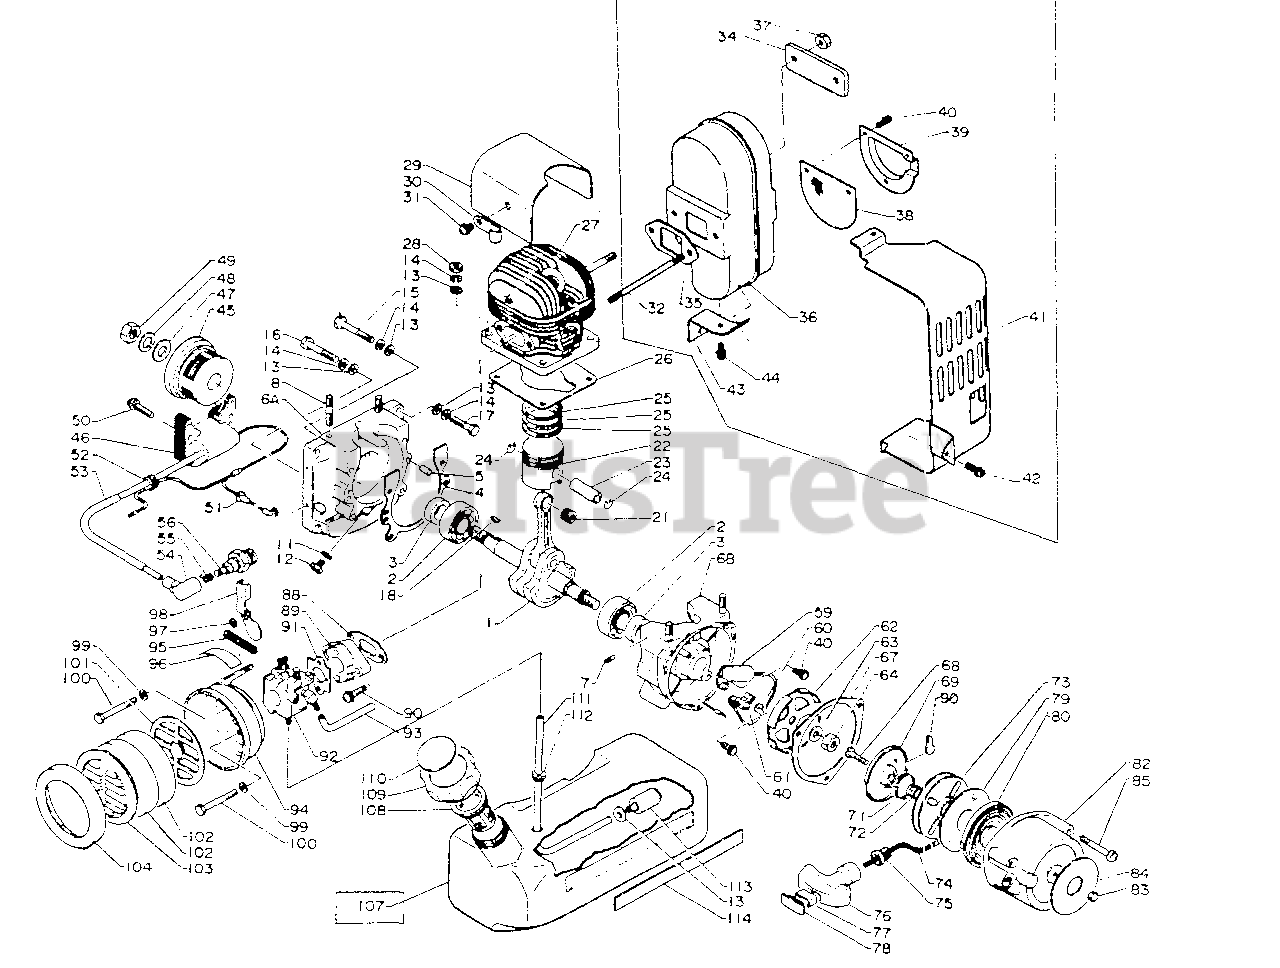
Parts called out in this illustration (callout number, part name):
1	CRANKSHAFT ASSY
2	BEARING, BALL 6202
3	SEAL, OIL
4	GASKET, CRANKCASE
5	PIN, LOCATING 5×10
6	CRANKCASE KIT
6A	CRANKCASE KIT
7	CONNECTOR
12	BOLT, DRAIN
13	WASHER 6.5×11.5×0.8
14	WASHER, SPRING 6
15	BOLT
16	BOLT
17	BOLT 6×25
21	BEARING, NEEDLE
22	PISTON
23	PIN, PISTON
24	RING, SNAP 8
25	RING, PISTON
26	GASKET, CYLINDER
27	CYLINDER
28	NUT, HEX M6
29	COVER, CYLINDER
30	CLIP, CORD
31	BOLT 6×10
32	BOLT, STUD
35	GASKET, EXHAUST
36	MUFFLER
37	LOCKNUT - 6
38	SCREEN, SPARK ARRESTER
39	GUIDE, EXHAUST
40	SCREW 4×10
41	COVER, EXHAUST
42	SCREW 5×12
43	SUPPORTER
44	SCREW 5×10
45	FLYWHEEL
46	COIL, IGNITION
48	WASHER, SPRING
50	SCREW 5×25
53	TUBE, INSULATOR
54	CAP, SPARK PLUG
55	TERMINAL, SPARK PLUG CAP
56	SPARK PLUG - BM6A
59	CONDENSER
60	CLIP, CORD
61	CONTACT POINT SET
62	PAWL CATCHER
63	WASHER, CLUTCH
67	GASKET, STARTER
69	PLATE, FRICTION
70	RATCHET
71	SPRING
72	SPRING
73	REEL, ROPE
74	ROPE, STARTER 4.0×880
75	GUIDE, ROPE
76	GRIP, STARTER
77	RING, RETAINING
78	COVER, HANDLE
79	PLATE, STARTER
80	SPRING, RECOIL
82	CASE, STARTER
83	NUT - 5 -- CAP
84	LABEL, ECHO
85	SCREW 5×42
89	INSULATOR
90	SCREW 6×25
91	GASKET, INTAKE
92	CARBURETOR - WA-55
93	PIPE
94	CASE, AIR FILTER
95	GROMMET
96	LABEL - CHOKE
97	WASHER 5.5×8×0.8
98	SHUTTER, CHOKE
99	WASHER
100	BOLT
101	RETAINER, AIR FILTER
102	FILTER, AIR
103	COVER, AIR FILTER
104	COVER, AIR FILTER
107	TANK, FUEL
108	FILTER, FUEL
109	CAP ASSY
110	LABEL - FUEL MIX
111	PIPE, FUEL W/GROMMET 3×5×250L
112	GROMMET
113	FILTER, FUEL
114	LABEL - NAME
